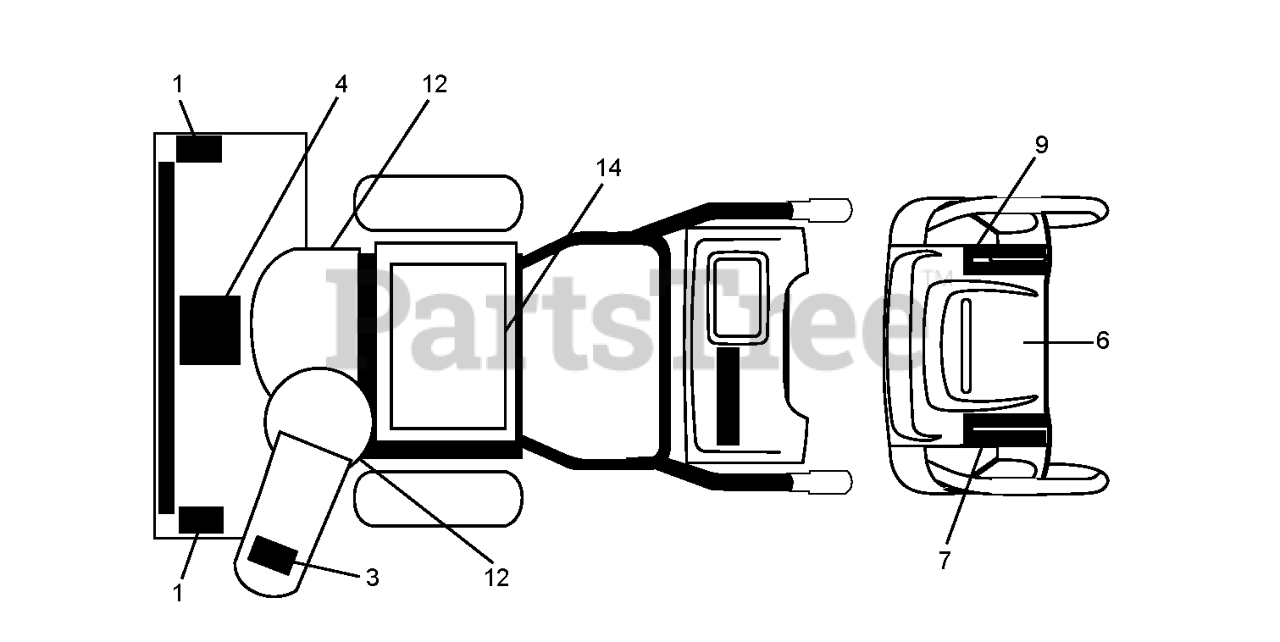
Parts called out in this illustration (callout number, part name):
1	DECAL.AUGER.SAFETY.
3	DECAL.CHUTE.SAFETY.
4	DECAL.AUGER."
7	DECAL.CONS.LT.SPD/LEV/PWRST.
9	DECAL.CONS.RT.SPD/LEV/PWRST.
12	DECAL.BELT.GUARD.
14	DECAL.FENDER
